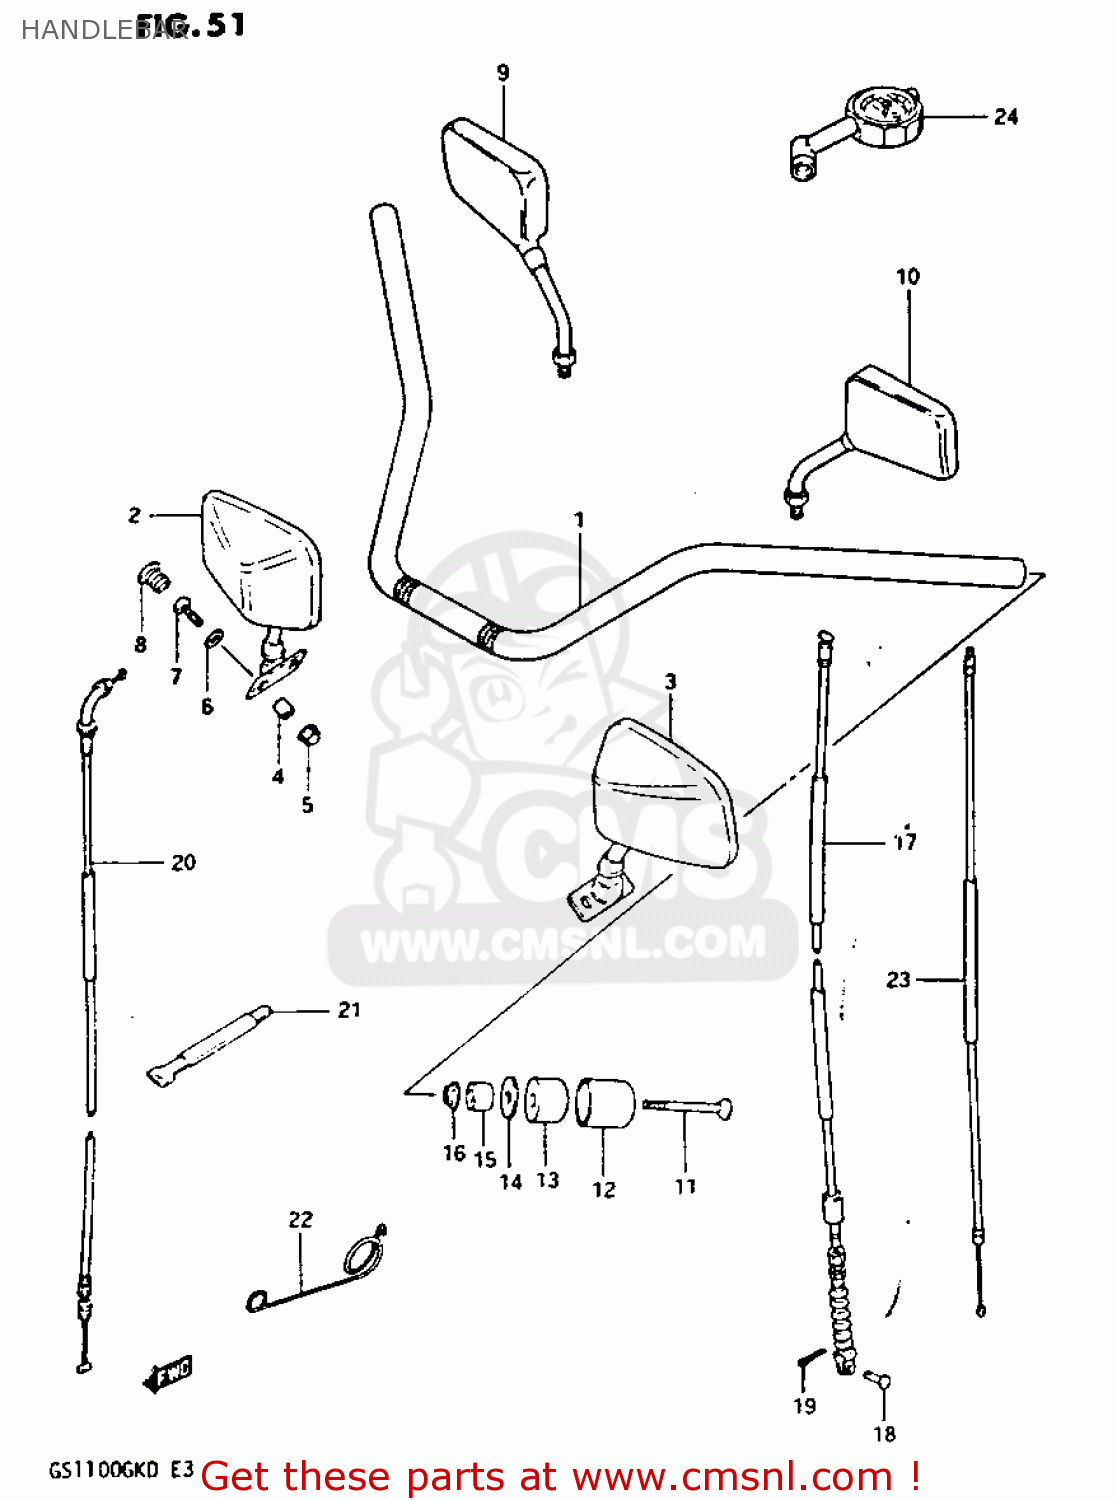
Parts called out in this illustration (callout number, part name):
1	HANDLEBAR
2	MIRROR ASSEMBLY,RIGHT
3	MIRROR ASSEMBLY,LEFT
4	SPACER(6.3X9.3X16.5)
5	NUT
6	WASHER
7	SCREW
8	CAP(OD:14)
9	MIRROR ASSEMBLY,REAR VIEW
10	MIRROR ASSEMBLY,REAR VIEW
11	SCREW
12	CAP,BALANCER
13	BALANCER,HANDLE
14	SPACER,BALANCER
15	EXPANDER,HANDLE BALANCER
16	NUT
17	CABLE ASSY,CLUTCH
18	PIN(L:15)
19	PIN
20	CABLE ASSY,THROTTLE
21	CLAMP
22	GUIDE,CLUTCH CABLE
23	CABLE,STARTER
24	GAUGE ASSY,AIR PRESSURE
